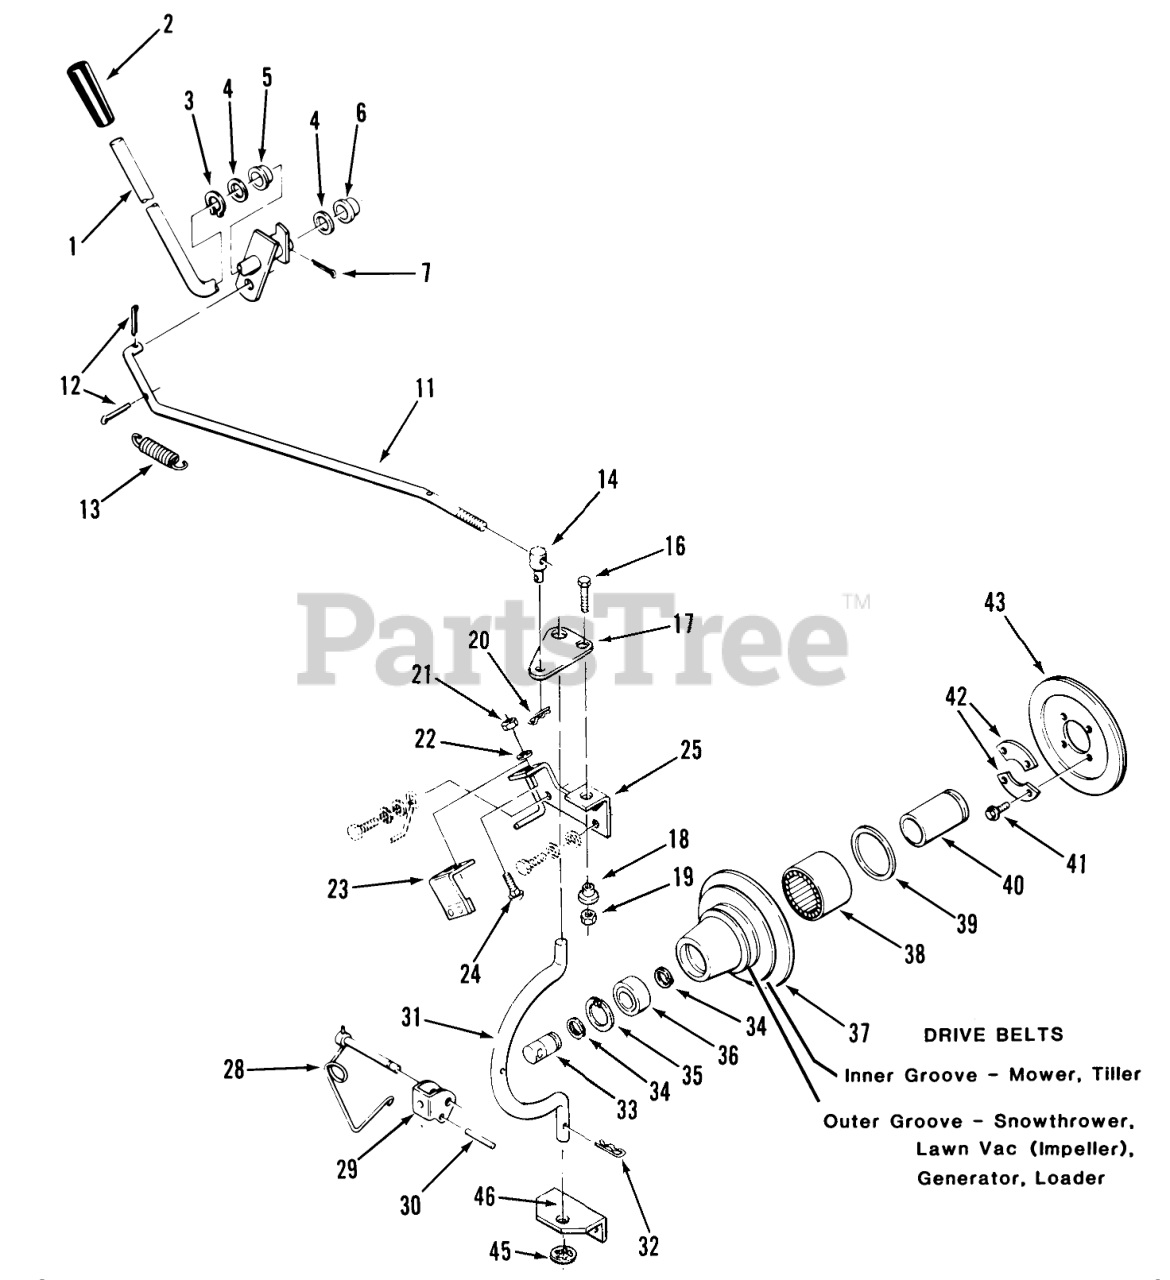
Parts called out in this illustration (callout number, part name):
1	ASSY PTO CLUTCH LEVE
2	GRIP
3	Grip Ring
4	SHIM-WASHER
5	BUSHING-NYLINER
6	NYLINER BUSHING
7	Pop Rivet
11	ROD-PTO CLUTCH
12	Pop Rivet
13	SPRING
14	TRUNNION
16	BOLT
17	PLATE
18	SPACER-LIFT LINK
19	Nut
20	Hairpin Cotter
21	Nut
23	ASM-Bracket
24	Bolt-Carriage
25	ENG BRACKET WAB
25	BRACKET-ENGINE B
28	LOCKING PIN ASM
28	Locking Pin 420-LSE Only
29	CLEVIS B
30	Spirol Pin 5/32 x 1 3/8
31	ROD-HOUSING
32	Hairpin
33	SHAFT-PTO
34	RING-SNAP, EXTERNAL
35	Snap Ring 1 3/4 Internal
36	BEARING-BALL
37	Housing-Clutch
38	BRG-NEEDLE OPEN END
39	SEAL-OIL
40	RACE-BEARING
40	BEARING RACE
41	H H C S
42	RETAINER
43	Clutch Plate & Facing
45	RING-REINFORCED CIRC
46	Axle
